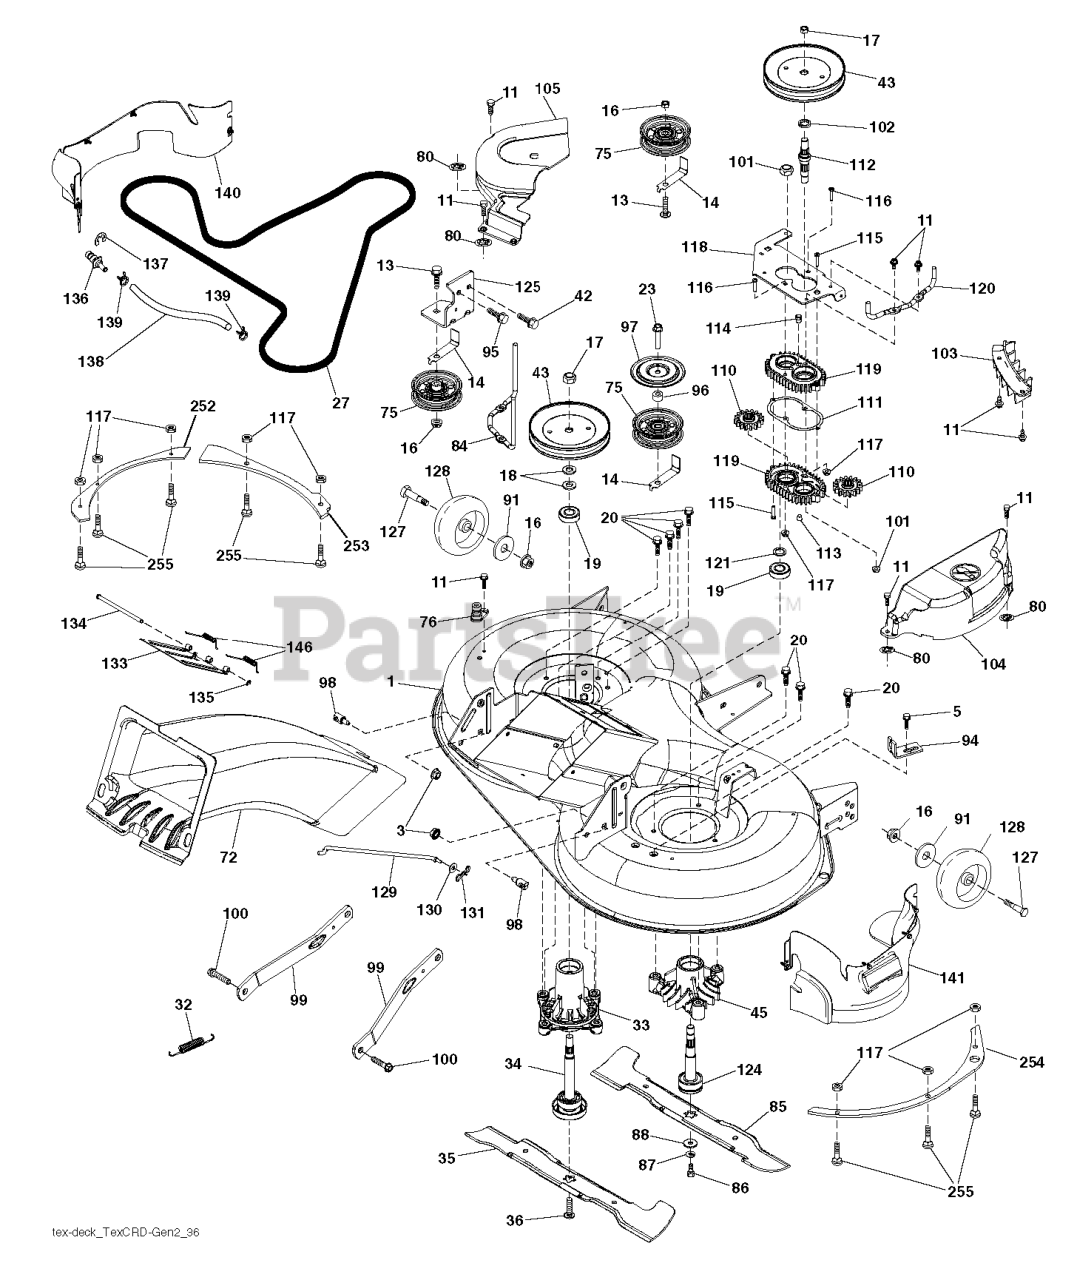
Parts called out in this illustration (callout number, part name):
1	DECK.SVC.WLDT.97EL.TCRD.EZ.498
3	NUT LOCK HEX FLANGE 5/16-18
5	BOLT.5/16HEX.WHS.HD
11	SCREW.1/4-20X5/8
13	BOLT.3/8-16X1.50
14	KEEPER, BELT IDLER
16	NUT LOCK FLG 3/8-16 UNC
17	NUT.FLANGE.LOCK.TOP
18	WASHER.SPACER.MANDREL
20	SCREW, WASHER HEAD
23	SCREW LT
27	BELT 97CM ELECTRIC
32	SPRING 107CM & 97CM ELECTRIC D
33	RP.HOUSING.MANDREL.4PT.
34	SHAFT.ASM.MDRL.N/GREASE.38
35	BLADE.3N1.LH.CRD.97
36	BOLT.WASHER.ASM.7/16-2
42	SCREW
43	PULLEY.MANDREL.5.0.PD.38"
45	HOUSING.MANDREL.44/46" VENT
72	CHUTE.107/97.TEX.GEN2.TRIMMED
75	FLAT IDLER PULLEY
76	1/2" BARB.DECK.WASHOUT.PORT
80	PALNUT 1/4
84	BELT KEEPER.MANDREL.38"COATED
85	BLADE.3N1.RH.CRD.97
86	BOLT.3/8-24X1.25GR8. LHTHRD
87	LOCKWASHER
88	WASHER.BLADE
91	WASHER
94	BRKT.CLUTCH.CABLE
95	SCREW, 3/8-16X3/4
96	SPACER
97	PROTECTOR
98	STUD.FASTNER.W/ANTI-ROTATE
99	ARM.SUSPENSION.MOWER.R
100	BOLT.SHOULDER
101	NUT.CROWNLOCK.9/16 -18.UNC
102	SPACER BEARING
103	GUARD GUARD FRONT VENT
104	97.CRD.RH.MANDREL.COVER
105	MANDREL MANDREL COVER LH
110	CRD.SPUR.GEAR
111	GASKET GASKET GEARCASE
112	SHAFT SHAFT. CRD GEARCASE ADAP
113	PLUG PLUG OIL
114	VALVE VALVE RELIEF
115	SCREW
116	BOLT.CARIGE.SS.1/4-20X1.75GR5
117	NUT T
118	ARM ARM CLUTCHING
119	GEARCASE GEARCASE SUBASM
120	BRACKET KEEPER BELT RH
121	WASHER WASHER
124	MANDREL SHAFT NON/GREASE
125	BRACKET BRACKET IDLER CHASSES
127	BOLT.SHOULDER.3/8-16X3-5/8.
128	RP WHEEL. GUAGE RALLY
129	ROD ROD. SWAY CRD GEN II
130	WASHER
131	PIN.COTTER.5/16.BOW TI
133	DOOR
134	PIN PIN.HINGE
135	E-RING.5/16"
136	PLUG WASHOUT PORT HOOKUP
138	HOSE.3/8ID.BULK.12"
139	HOSE.3/8.CLAMP (2 2)
140	GUARD
141	GUARD SUBASM.TEX CRD 97CM RH F
146	SPRING SPRING: EZ MULCH DOOR
252	PLATE 97 LEFT BOLT REINFORCING
253	PLATE 97 LH SIDE BOLT ON
254	PLATE 97 RH SIDE BOLT ON
255	RHSNB, 1/4-20 X 1, GR5
